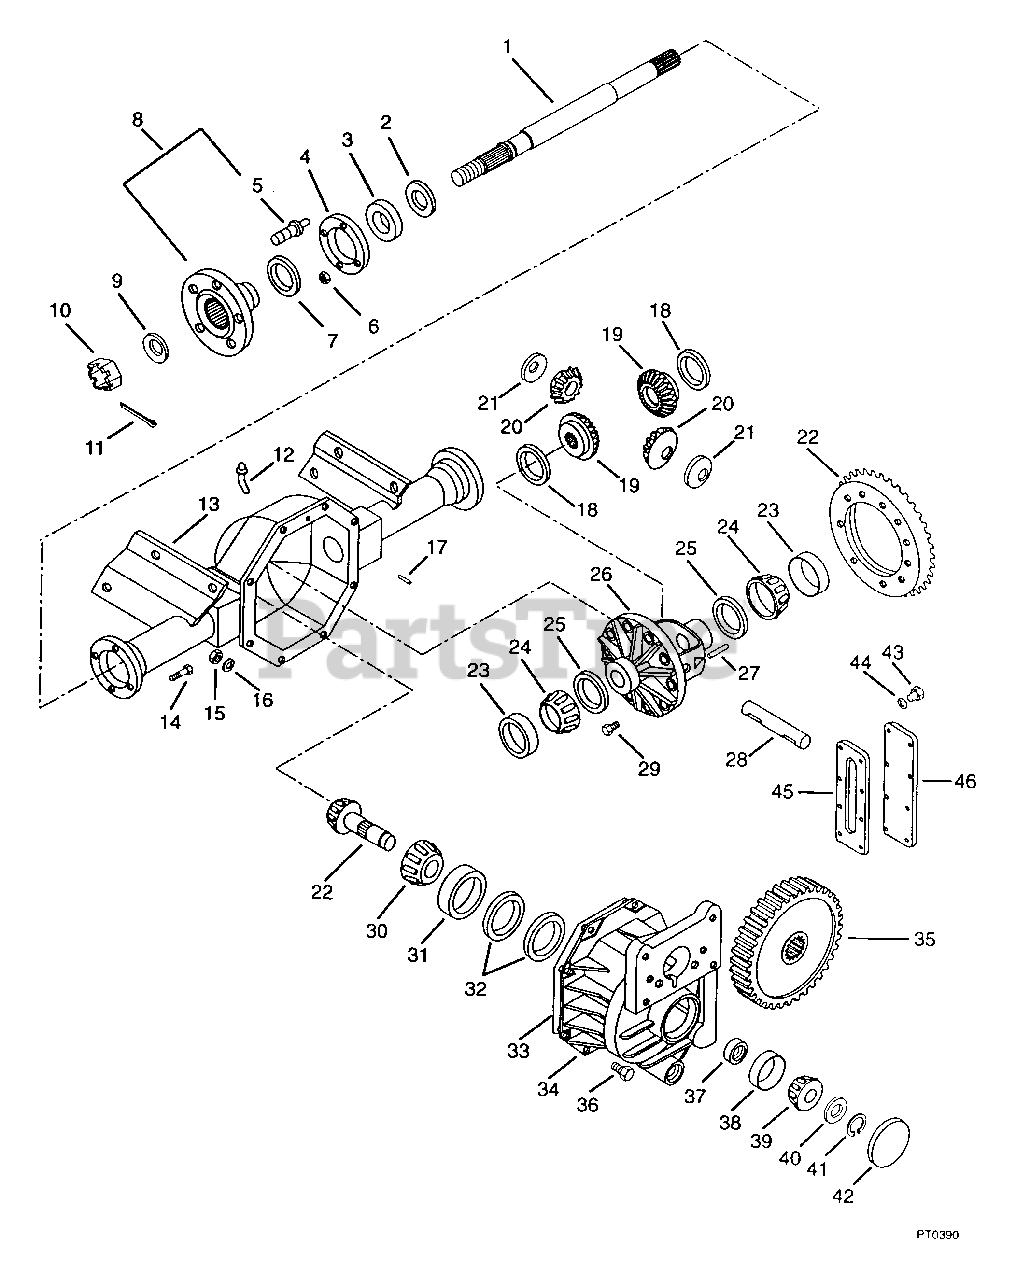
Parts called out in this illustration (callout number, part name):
1	AXLE SHAFT LH
1	AXLE SHAFT RH
2	SEAL 1.183X1.183X.265
3	BRG-CONE 46MMX17MM
4	GASKET-SEE LETTER L-307
5	CARRIER LUG BOLT
6	NUT-LK-FLG .312-24 GR C
7	FELT SEAL
8	AXLE FLANGE ASSEMBLY
9	WSHR-FL-STL .875X1.500X.1196
10	NUT-SL .875-14
11	PIN-COTR .15X1.50
13	LOWER HOUSING
14	BLT-HEX .31-24X1.25 GR8
15	NUT-HEX .312-18
16	WSHR-LK-INT .313X.030 PL
17	DOWEL PIN
18	WSHR-FL-STL 1.578X2.375X.031
19	SIDE GEAR
20	BEVEL GEAR
21	WSHR-BLVL .703X1.593X.031
22	PINION & GEAR
23	BRG-CUP 2.892X.580
24	BRG-CONE 1.63X.78
26	DIFFERENTIAL CASE
27	LOCK PIN
28	PINION SHAFT
29	BLT .38-24X.812 DANA
30	BRG-CONE 1.188X.84
31	BRG-CUP 2.532X.656
34	FRONT HOUSING W/BRG CAP & SCRE
34	FRONT HOUSING W/BEARING CAP &
35	SPUR GEAR
36	BLT-HEX .31-18X1.00 PL GR5
37	FRONT PINION BEARING SPACER
38	BRG-CUP 1.968X.550
39	BRG-CONE .844X.72
40	SHIM ASSEMBLY
41	RG-RTNG-EXT .813X.042
42	CUP PLUG
43	TAPTITE M5-0.8X16MM H-FL-PL
44	WSHR-LK-EXT 12X.025 PL
46	SIDE COVER
